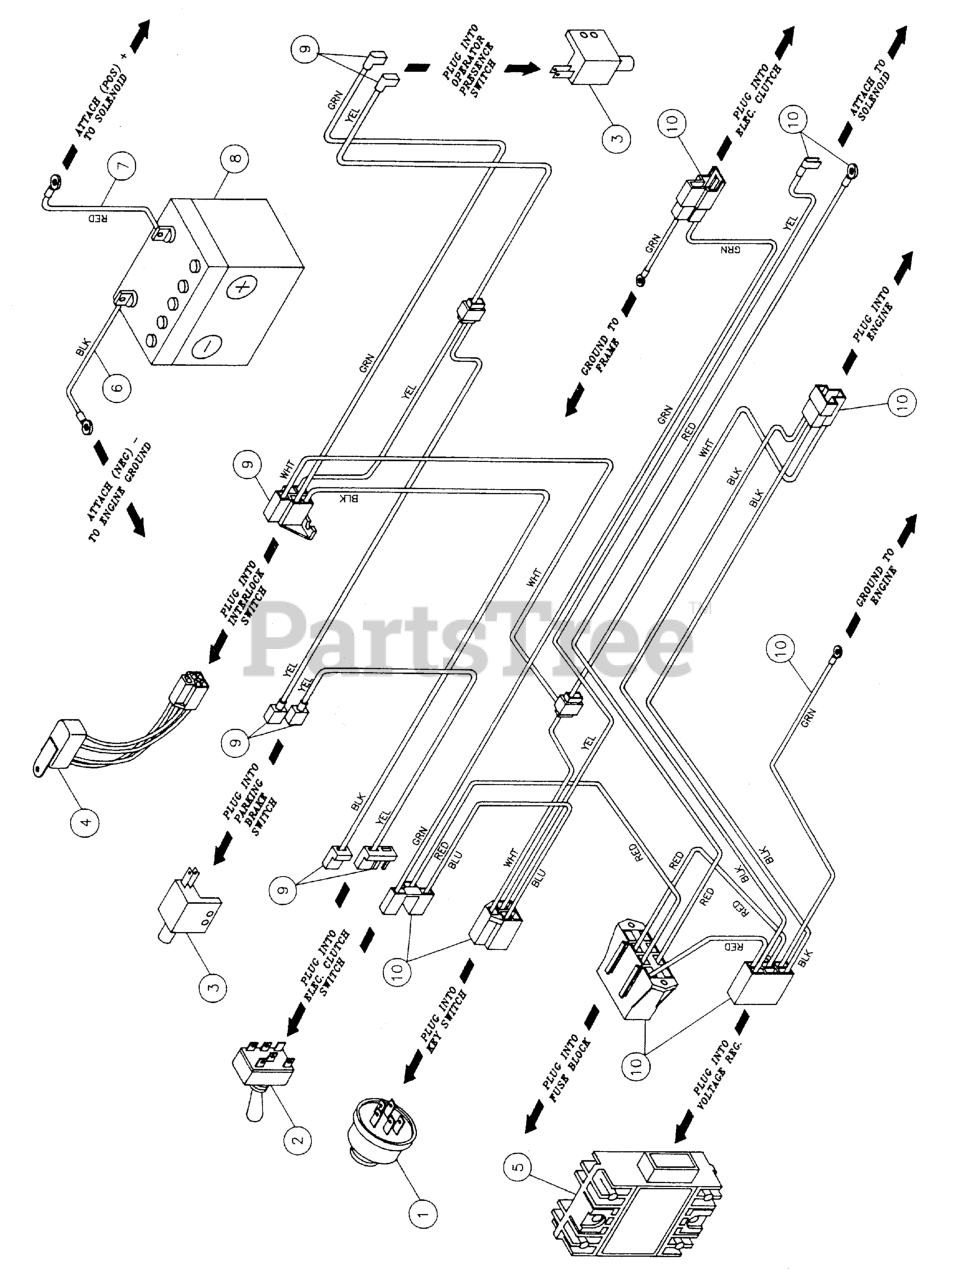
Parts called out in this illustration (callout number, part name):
1	SWITCH, Ignition
2	SWITCH, Electric Clutch
3	SWITCH, Plunger, NO
4	Saftey Interlock
6	BATTERY CABLE, NEG, 22, 1/4-5/16
7	POSITIVE (+) BATTERY CABLE, 30"
8	BATTERY, Lawn & Garden, 12V (BCIU1, 340 CCA)
9	Interlock Electrical Harness
10	Fuse Block Electrical Harness
